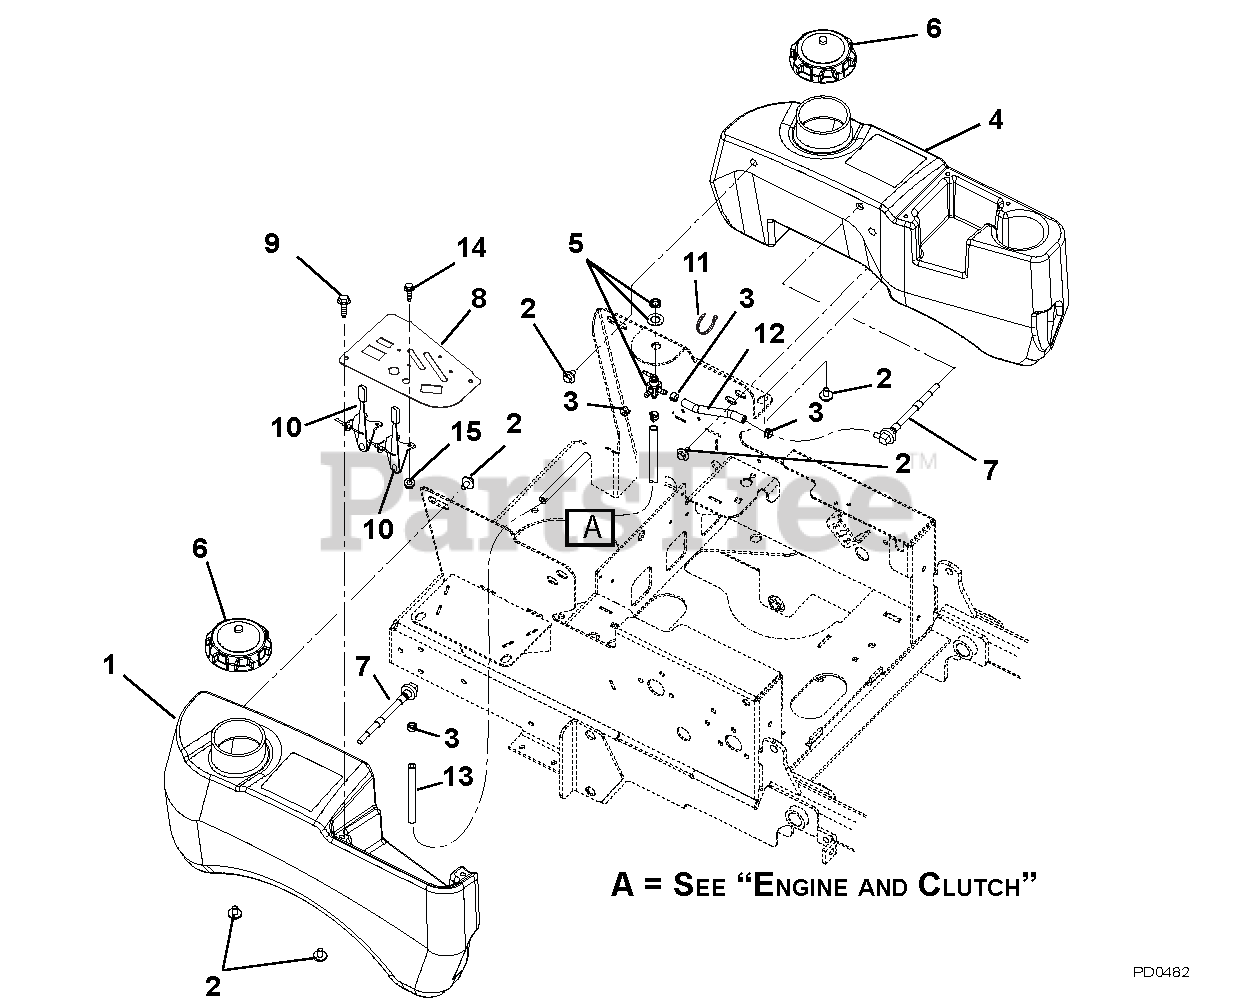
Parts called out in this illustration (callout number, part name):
1	TANK, FUEL RH W/O HOSE
2	BOLT, SEMS .31-18 X .62
3	CLAMP, FUEL LINE
4	TANK, LH FUEL CZ W/O HOSE
5	VALVE, FUEL
6	CAP, FUEL
7	ASS'Y, SMALL TANK FUEL PICK-UP
8	PANEL - CONTROL
9	SCR-MCH 10-24X.38 HWHSTAINLESS
10	CABLE, CONTROL
11	CABLE TIE LG 5-1/2
12	HOSE, .25 LOW-PERM BULK GAS
13	HOSE, .25 LOW-PERM BULK GAS
14	@SCR-MCH 10-24X.50 HWH YWZC
15	@NUT-LK-NYL 10-24 W/INSRT YWZC
